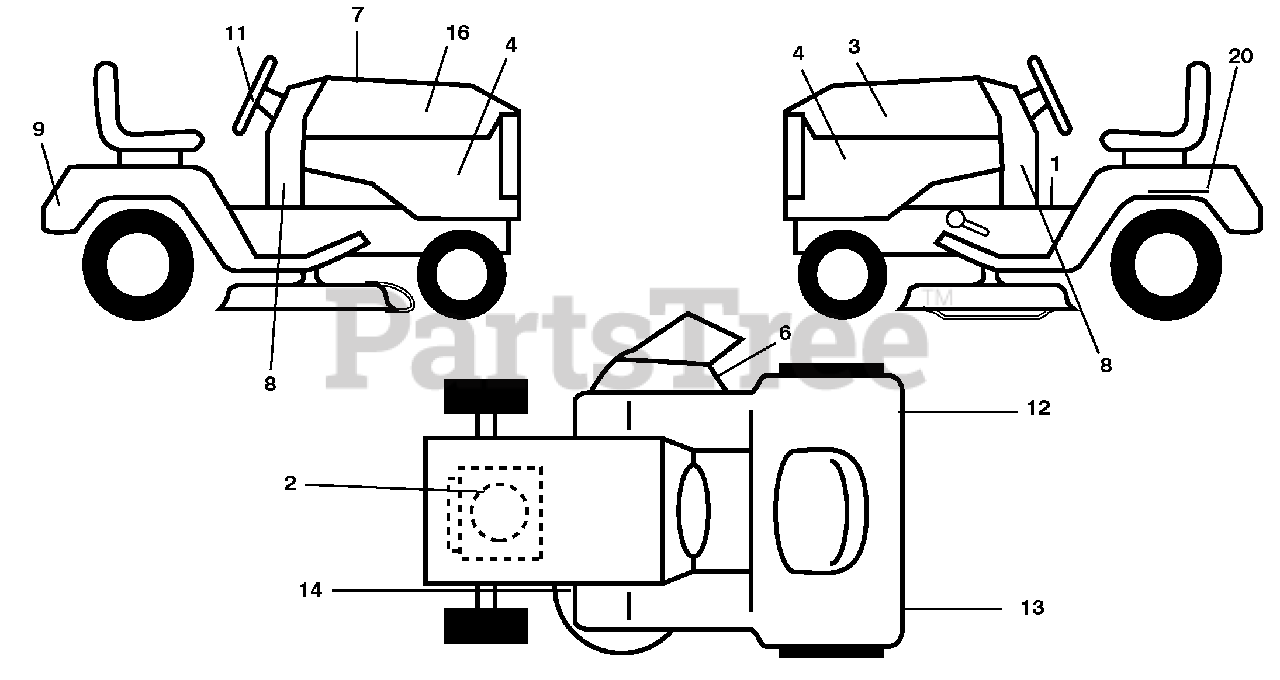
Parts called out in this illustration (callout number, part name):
1	Decal Oper
2	Decal Engine H.P.
3	Decal Hood LH
4	Decal Side Panel
6	Decal Warning, Keep Hand Away
7	Decal Replacement Parts
8	Decal LWRDASH
9	Decal Fender Logo
11	Decal Ins Strg Whl
13	Decal Fender SD LH
14	Decal V-Belt Schematic
16	Decal Hood Rh
20	Decal Bat Dan/Psn
20	Pad Footrest LH
20	Pad Footrest RH
20	Decal Bypass
20	Manual Operator's E&F
20	Manual Parts
